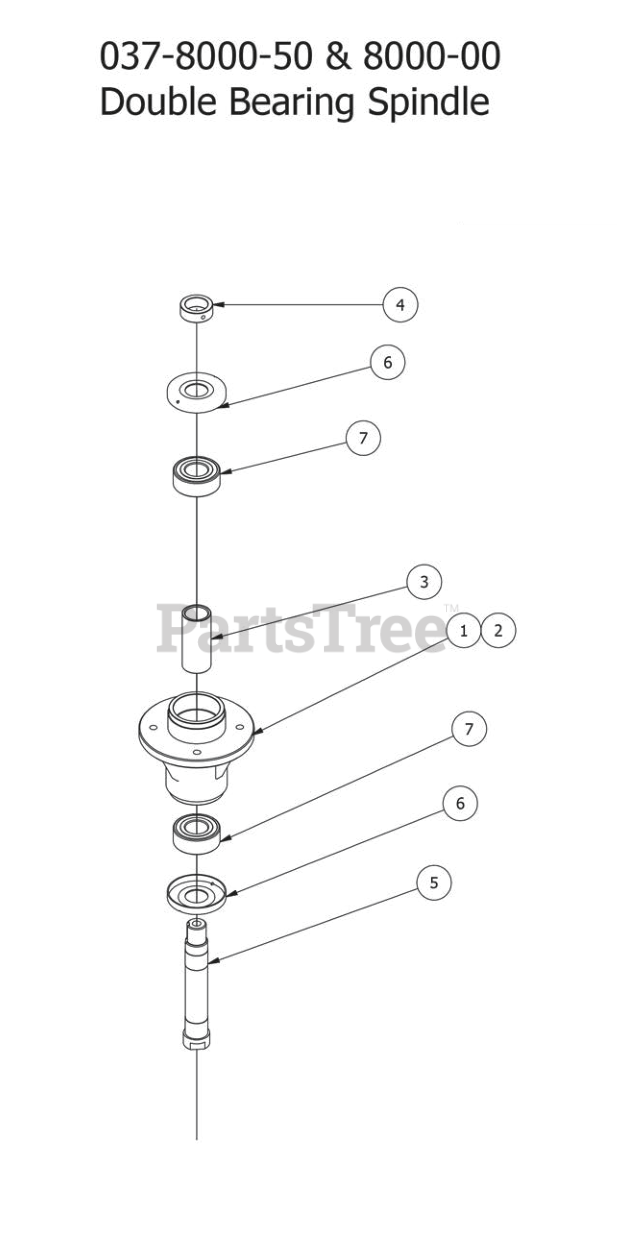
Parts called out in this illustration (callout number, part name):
1	Aluminum Spindle Housing
2	Spindle Housing -Dble Brg
3	Tube Spacer Double Bearing Spindle
4	Collar Spacer - Top of Spindle
5	Short Spindle Shaft w/Locking
6	Dust Cover
7	Double Bearing for spindle
